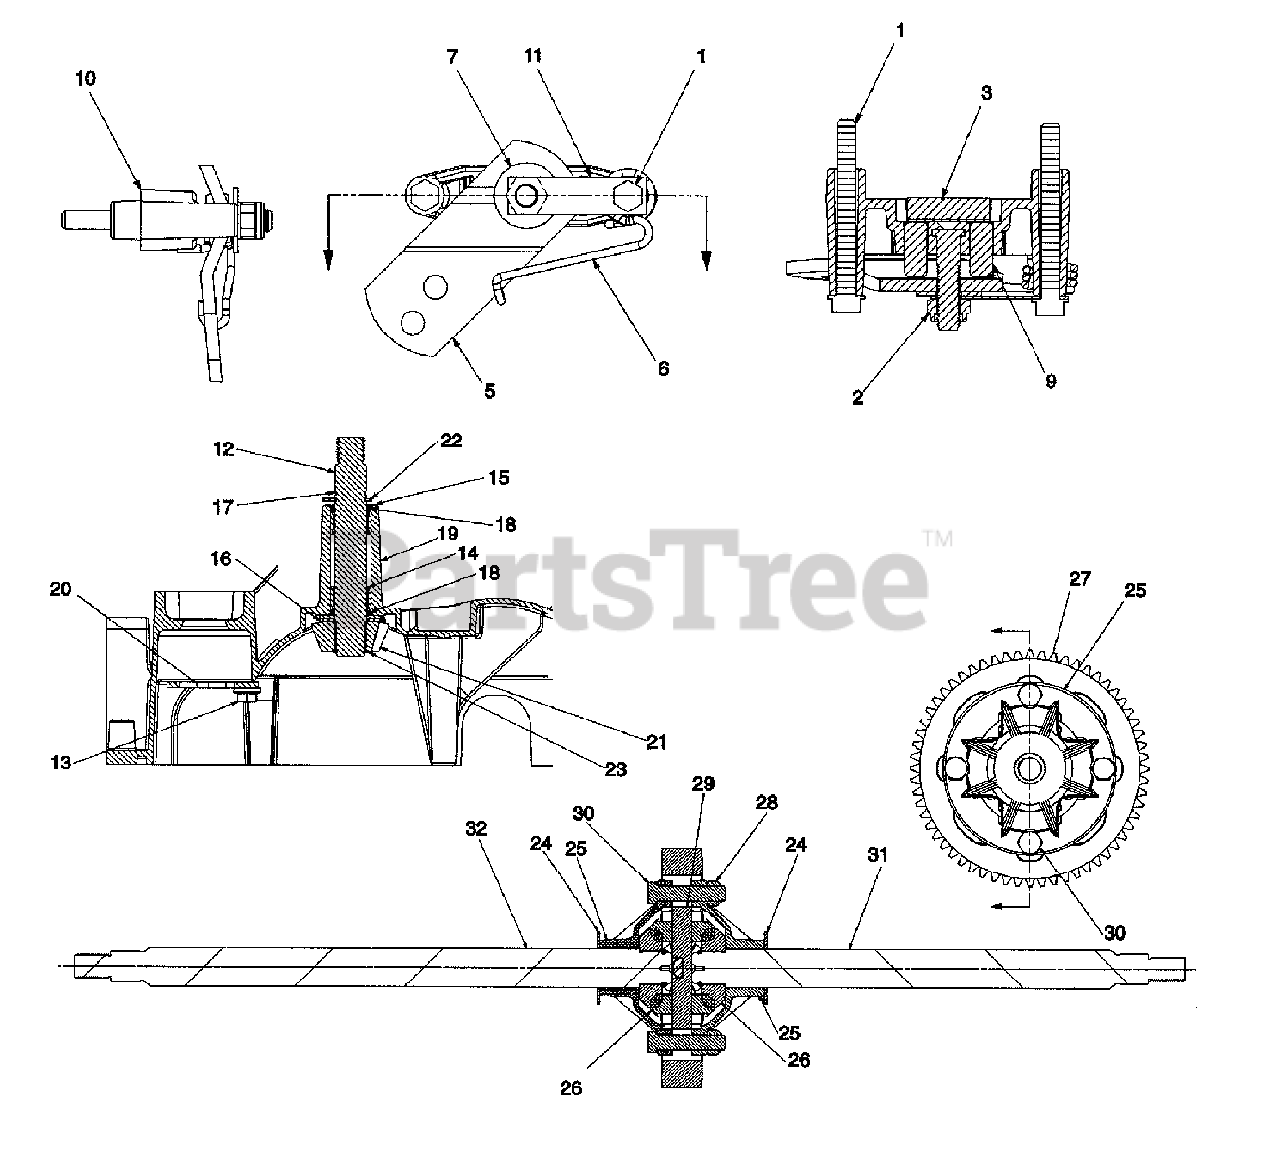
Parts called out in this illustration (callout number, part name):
1	Hex Wash. Hd. Scr. 1/4-20 x 2.37
2	Nylon L-Nut 5/16-24 Thd.
3	Brake Puck
5	Brake Arm
6	Torsion Spring
7	Fl-Wash. .343" I.D. x .88" O.D.
9	Brake Pin
10	Brake Yoke
11	Brake Anti Rotation Brkt.
12	Input Shaft
13	Hex Wash. Hd. AB-Tap Scr. 1/4-14 x .625" Lg
14	Needle Brg. .625" I.D.
15	Fl-Wash. 5/8" I.D. x 1" O.D.
16	Thrust Wash. .635" I.D. x 1.25" O.D
17	Wire Ring
19	Upper Housing
20	Lockout Plate
21	Bevel Gear
22	Retainer Ring
23	Retainer Ring
24	Fl-Wash. 1" I.D. x 1.8" O.D.
25	Differential Housing
26	10T Miter Gear
27	Spur Gear 60T
28	Hex L-Nut 3/8-24 Thd.
29	Cross Shaft
30	Hex Bolt 3/8-24 x 1.75" Lg. (Gr. 5)
31	Axle Ass'y.-L.H.
32	Axle Ass'y.-R.H.
